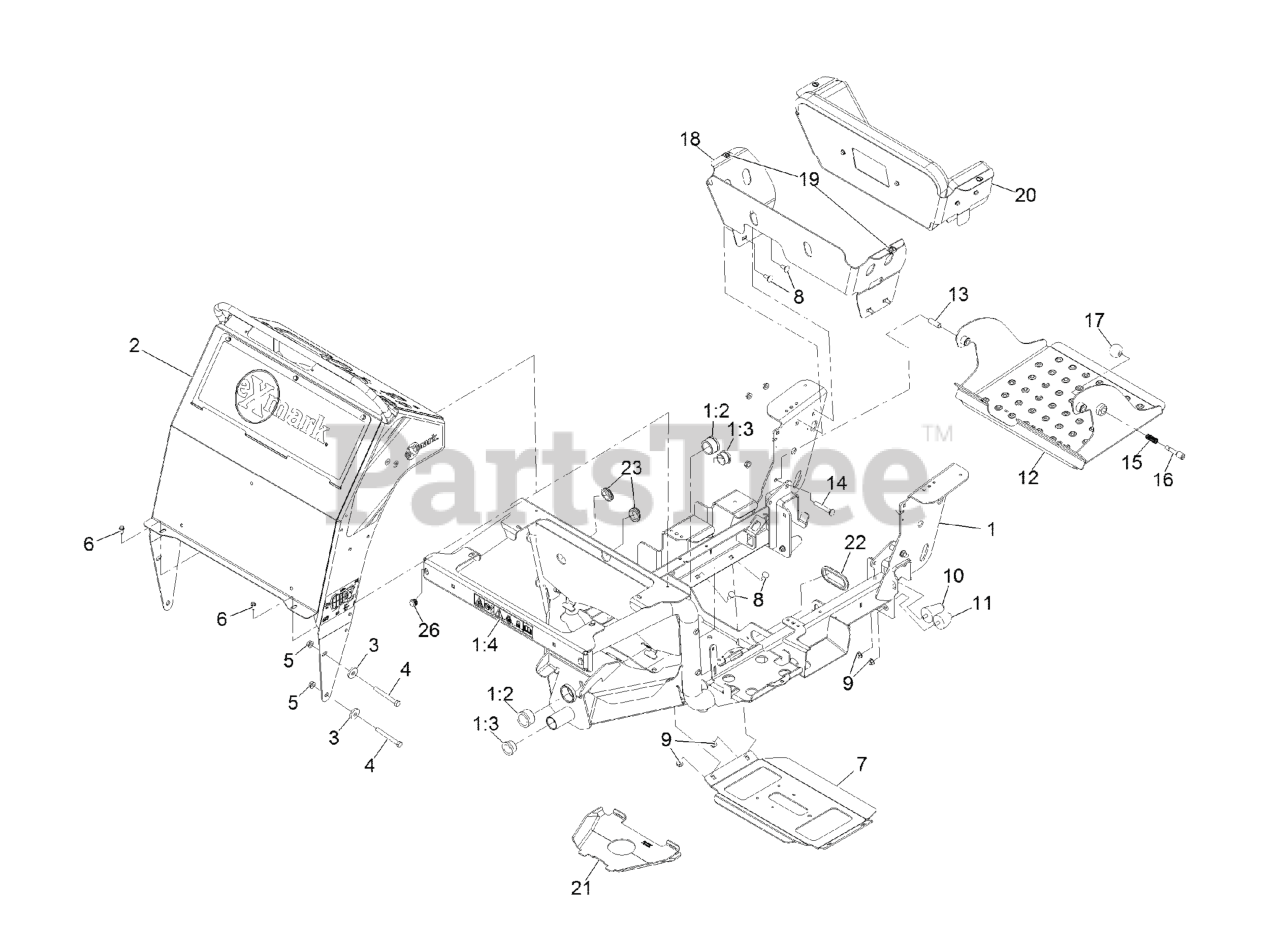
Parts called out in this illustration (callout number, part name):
1	FRAME ASM
1:2	BEARING-FLANGED
1:3	BEARING-FLANGED
1:4	DECAL-DOWN, TIE
2	CONTROL TOWER ASM
4	SCREW-HH
6	SCREW-HWH
7	GUARD-LOWER
8	SCREW-CARR
10	BUMPER-RUBBER
11	BUMPER-RUBBER
12	OPERATOR PLATFORM ASM
13	BUSHING-PIVOT, PLATFORM
14	SCREW-CARR
16	PIN-LATCH
17	KNOB-BALL
18	MOUNT-PAD, KNEE
19	RECEPTACLE-CLIP, MINI
20	Knee Pad ASM
21	SHIELD-DUST
22	GROMMET
23	GROMMET
26	PLUG-TUBE
